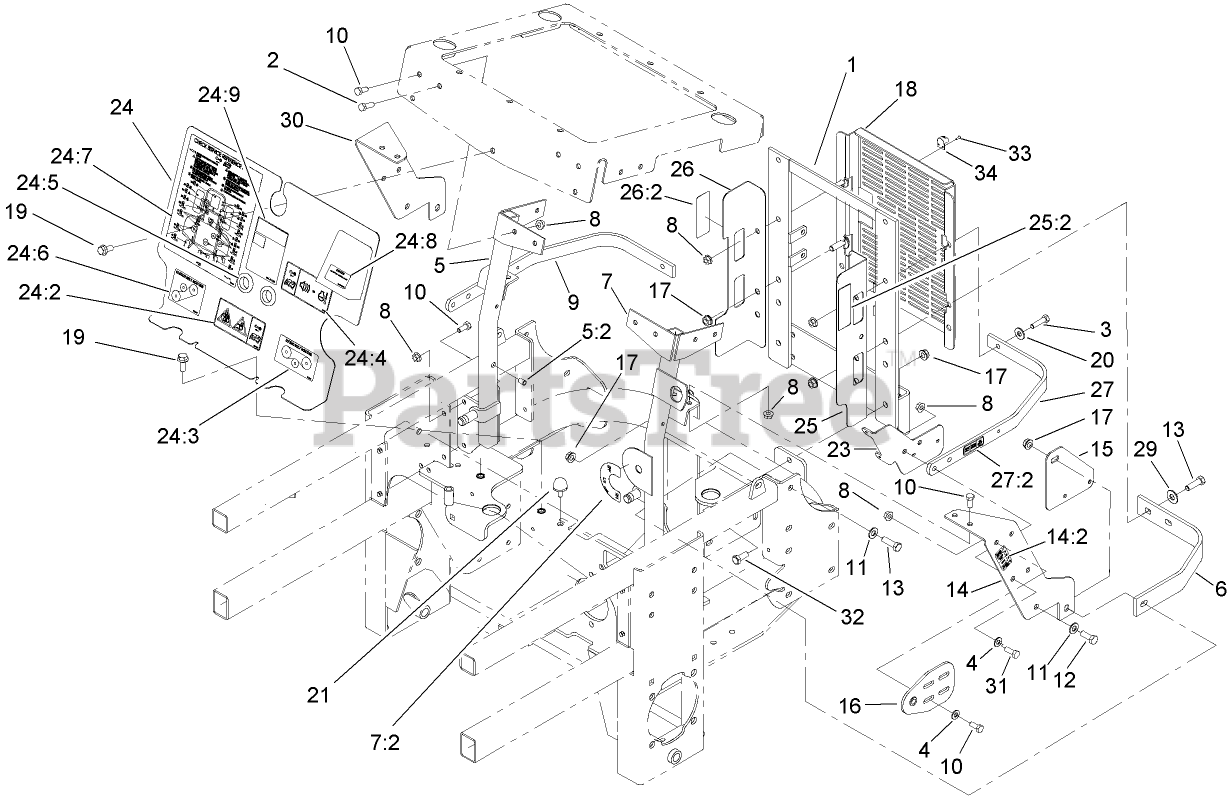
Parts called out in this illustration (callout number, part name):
1	SUPPORT-RADIATOR, REAR
2	SCREW-HH
3	SCREW-HH
4	WASHER-PLAIN
5	RH RADIATOR BRACE ASM
5:2	INSERT-THREADED
6	STRAP-GUARD
7	LH RADIATOR BRACE ASM
7:2	DECAL-VALVE, FUEL
8	NUT-HF
10	SCREW-HH
11	WASHER-FLAT
12	SCREW-HH
13	SCREW-HH
14	LH SUPPORT BRACKET ASM
14:2	DECAL-FUSES
15	BRACKET-PUMP, FUEL
16	PLATE-PIVOT, HOOD
17	NUT-HHF, WHIZ
18	SHIELD-COOLER
20	WASHER-FLAT
21	BUMPER-RUBBER
23	BRACKET-RELAY/FUSE
24	FRONT ENGINE SHIELD ASM
24:2	DECAL-DANGER, ROTATING DEVICES
24:3	DECAL-ROUTING, HYDRO BELT
24:4	DECAL- WARNING, BUZZER
24:5	GROMMET-RUBBER
24:6	DECAL-ROUTING, CLUTCH BELT
24:7	DECAL-CHECK, SERVICE
24:8	DECAL-CAUTION
24:9	DECAL-COOLANT
25	LH FAN GUARD ASM
25:2	DECAL-FAN, RADIATOR
26	RH FAN GUARD ASM
26:2	DECAL-FAN, RADIATOR
27	STRAP-TOP
27:2	DECAL-RELAY
29	WASHER-FLAT
30	BRACKET-SUPPORT, RH
31	SCREW-HH
32	SCREW-HH
33	RIVET
34	KEEPER-LATCH, RUBBER
